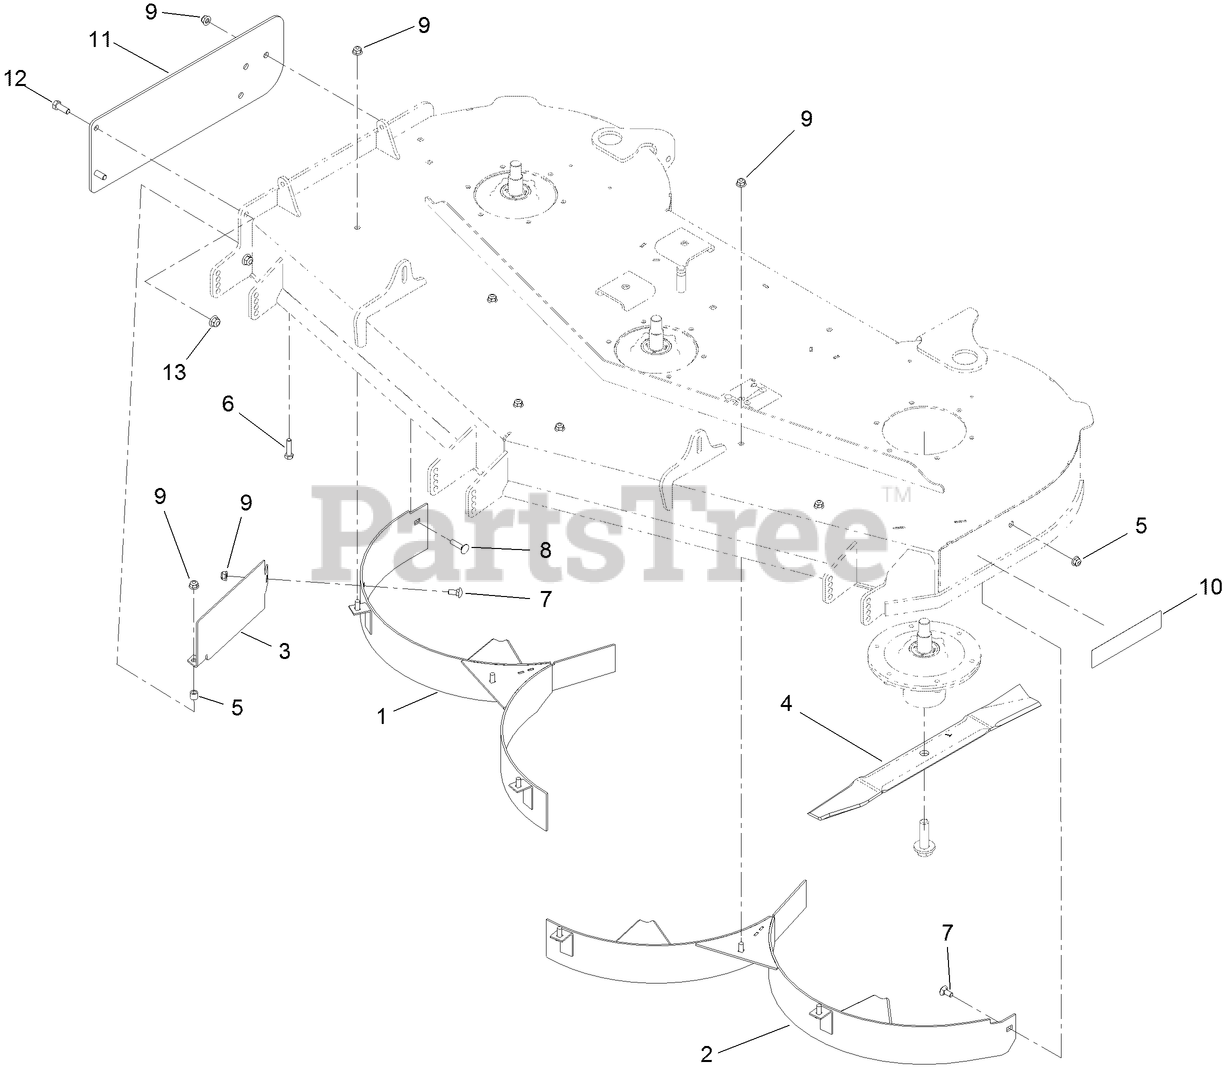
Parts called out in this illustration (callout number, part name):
1	BAFFLE-RH
2	BAFFLE-LH
3	GUARD-BAFFLE
4	BLADE - MULCH, 20.50 IN
5	SPACER
6	SCREW-HH
7	BOLT-CARR
8	SCREW-CARR
9	NUT-HF, NI
10	DECAL-RECYCLER, 60 INCH
11	PLATE-DISCHARGE, COVER
12	SCREW-HH
13	NUT-HF, NI
